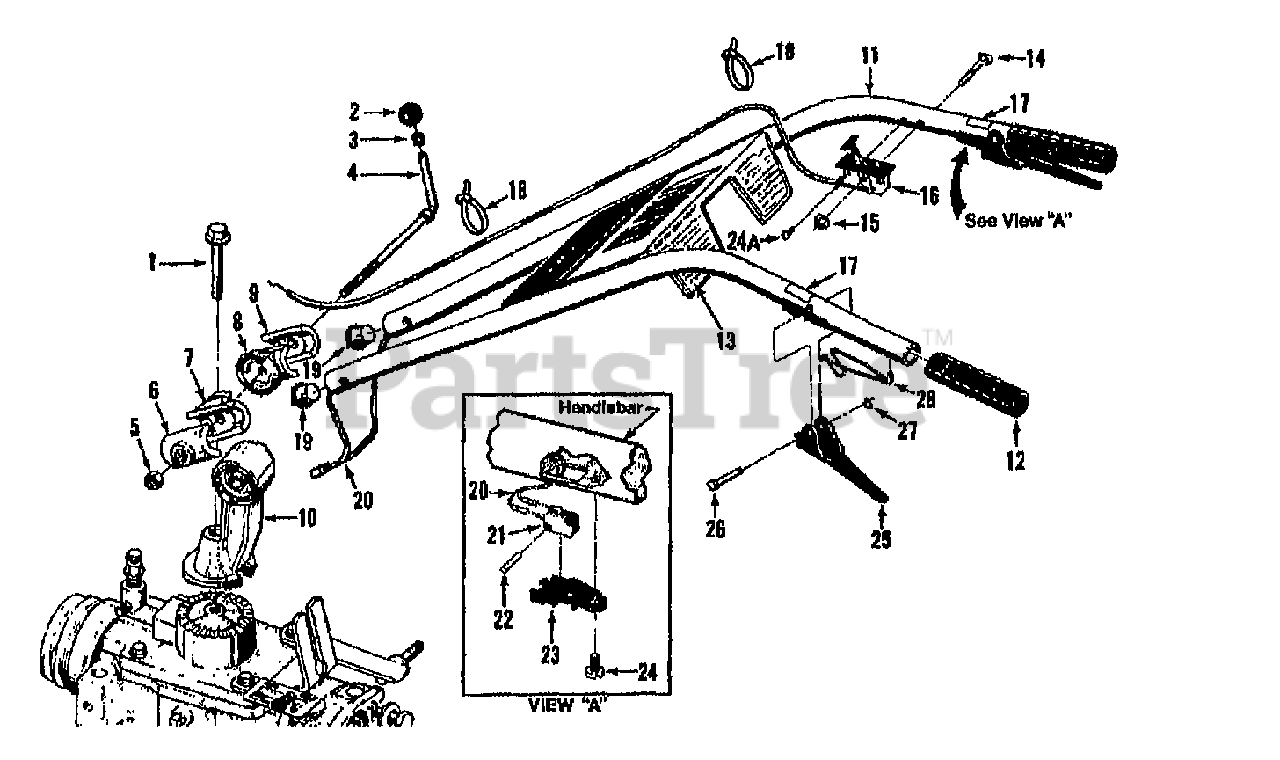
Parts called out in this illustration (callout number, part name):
1	BOLT 1/2-13X3.5 FH GR5
2	KNOB-CONTROL (INCL. 3)
3	RING-TOLERANCE .5325 ID
4	STUD-H/BAR W/NUT & RING (INCL. 2,3 & 5)
5	NUT-HEX JAM 1/2-13
6	CLAMP-LH HORSE 1021-1
7	RATCHET-H/BAR RED 2542-1
8	RATCHET-RH RED HORSE 2542-2
9	CLAMP-RH HORSE 1021-2
10	BASE-H/BAR RED 2534A
11	ASSM-HANDLEBAR W/GRIPS (INCL. 2 OF EA. 12, 17 & 28 AND ONE 13)
12	GRIP-H/BAR SMOOTH
13	DECAL-CONTROL PANEL HORSE
13	DECAL-CONTROL PANEL (11HP)
14	BOLT-CH 1/4-20X2.00 ZP
15	NUT-HF/LK 1/4-20 ZP
16	CABLE-THROTTLE 7 I/C B&S {12068/069/080/081/087}
16	CABLE-THROTTLE 7&8 B&S {12074/075/088/089/090}
16	CABLE-THROTTLE 8HP OPC {12070/071/082/083}
17	DECAL-FWD INTERLOCK
18	TIE-RED
19	RETAINER-HARNESS H/B OPC
20	HARNESS-WIRE OPC HORSE
21	SWITCH-H/B OPC
22	PIN-LK .11X.58 HORSE OPC
23	HOUSING-SWITCH OPC
24	SCR-HW M10-24X.5 STH ZP
24A	SCR-PHS M10-32X.5 STH ZP
25	LEVER-HORSE OPC
26	PIN-PIVOT OPC LEVER
27	RING-KLIP 5304-25
28	SPRING-H/B LEVER
